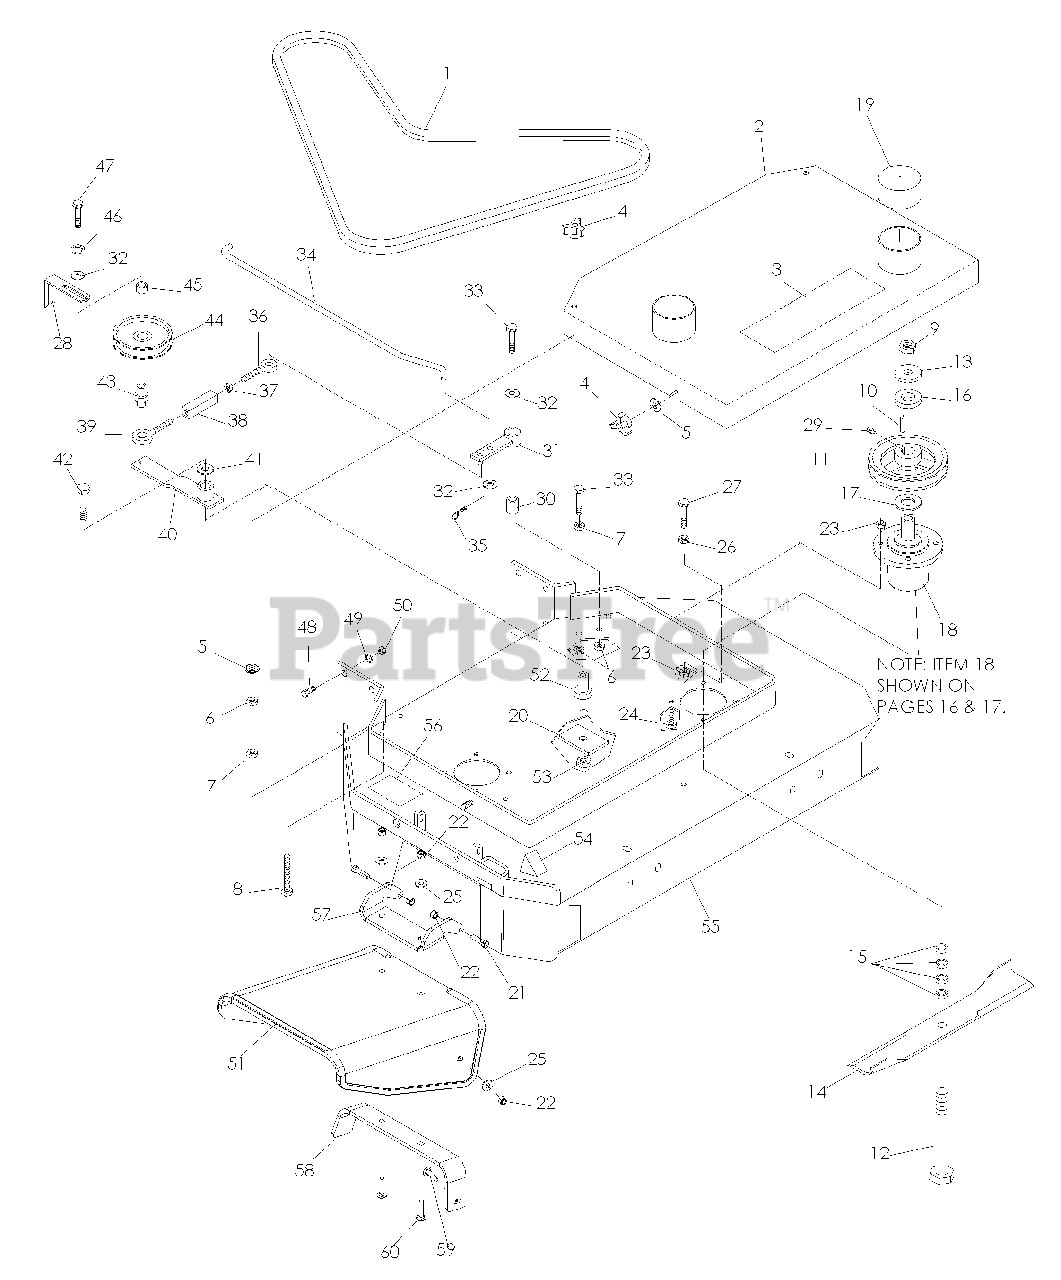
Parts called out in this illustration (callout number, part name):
1	DECK BELT, 36"
2	BELT SHIELD, 36"
3	DECAL, HUSQVARNA
4	THREE PRONG KNOB
5	WASHER 3/8 SEALING
6	HLN 3/8-16
7	NUT 3/8-16 WHIZ
8	TAPBOLT 3/8-16 x 4 1/2
10	KEY 1/4 SQ x 1 1/8
11	PULLEY W/SETSCREWS
12	HCS 5/8-18 x 8 1/2
13	WASHER, SUPPORT
14	BLADE 18" (36)
15	BLADE SPACERS
17	BUSHING 10 GA
18	HOUSING, CUTTER
21	HCS, 5/16 -18 x 1 1/4
22	NUT, 5/16 -18, NYLOC
23	HLN 5/16-18
24	HCS 5/16-18 x 1
25	WASHER, 5/16
26	HFLN 5/16-18
27	HCS 5/16-18 x 3
29	SETSCREW 5/16 NYLOC
30	SLEEVE BUSHING
31	ENGAGEMENT ARM
32	FW 3/8 STD
33	HCS 3/8-16 x 2 1/4
35	HAIRPIN #2
36	EYEBOLT RH
37	NUT 1/16-18
38	TURNBUCKLE
39	EYEBOLT LH
41	FW 1/2 STD
42	HCS 1/2-13 x 2 3/4
43	EYEBOLT PIVOT
44	IDLER PULLEY
46	LOCK WASHER 3/8
47	HCS 3/8-16 x 2 1/2
48	HCS 7/16-14 x 1 1/2
49	LOCK WASHER 7/16
50	NUT 7/16-14
51	DEFLECTOR CHUTE
52	IDLER SPINDLE
53	HLN 1/2-13 NYLOC
54	DECAL, CPSC
55	36" DECK W/DECALS
56	DECAL, SEVERING
57	PIVOT BRACKET
58	BRACKET, REINFORCE
59	RHSNB, 5/16 -18 x 1 1/4
60	RHSNB, 5/16 -18 x 1 1/2
